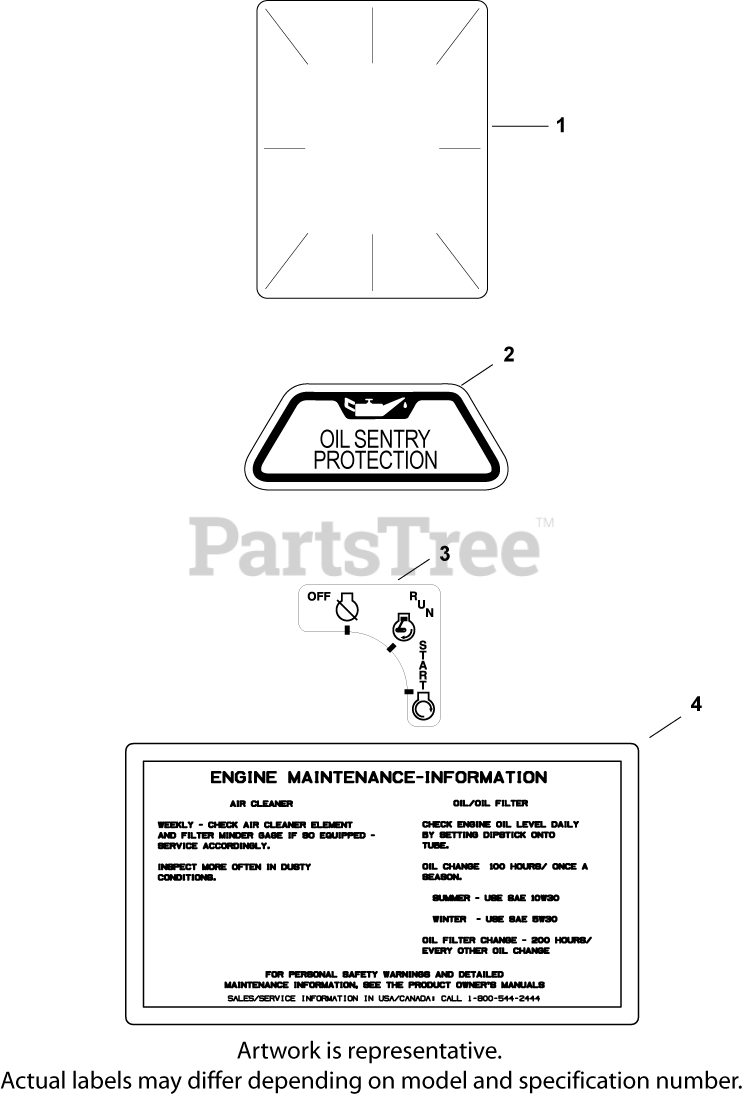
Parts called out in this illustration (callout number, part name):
1	DECAL, CLEAR LAMINATE USE 25 113 70-S
2	DECAL, OIL SENTRY - (#DSC)
3	DECAL, KEY SWITCH
4	DECAL, AIR CLEANER - (#DSC)
